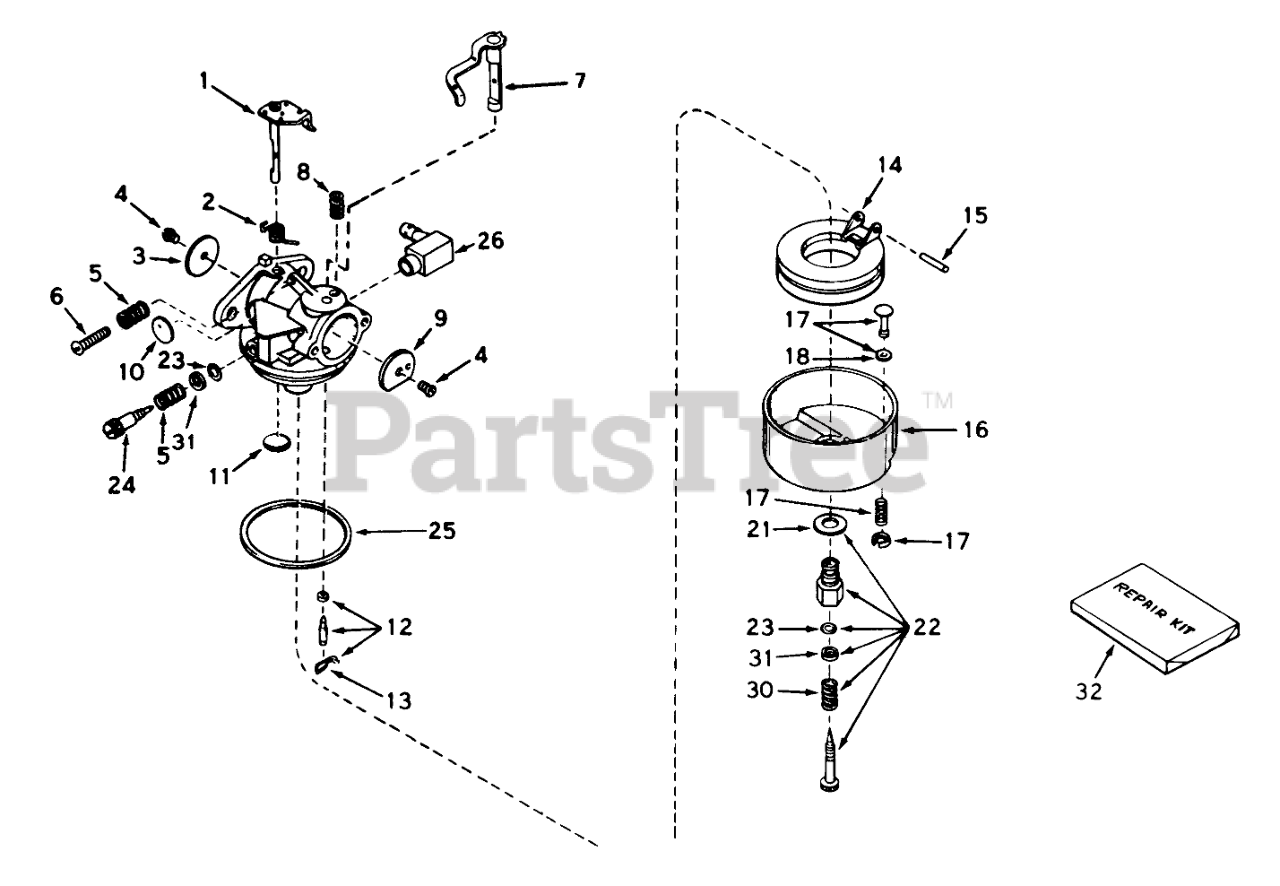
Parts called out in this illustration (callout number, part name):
1	Throttle Shaft and Lever ASM
2	Spring, Throtte Return
3	Shutter-Throttle
4	Screw-Shutter
5	Spring-Tension
6	Screw-Throttle Crack Screw / Idle Speed
7	Shaft/Lever Assy., Choke
8	Spring-Positioning, Choke
9	Shutter-Choke
10	Plug-Welch, Idle Mixture Well
11	Plug-Welch, Atmospheric Vent
12	Inlet Needle, Seat & Clip Assy.(Incl. No.13)
13	Clip-Spring
14	Float,Carburetor
15	Shaft-Float
16	Bowl-Float (no drain)
17	Plunger Assy., Drain (Incl. No.18)
18	Gasket-Plunger, Drain
21	Washer-Bowl Nut
22	Adjustment Screw Assy., Main (Incl. Nos. 21, 23, 30 & 31)
23	"O"Ring
24	Screw, Idle Adj.
25	O Ring-Bowl, Float
26	Fitting-Fuel
32	Kit-Repair
